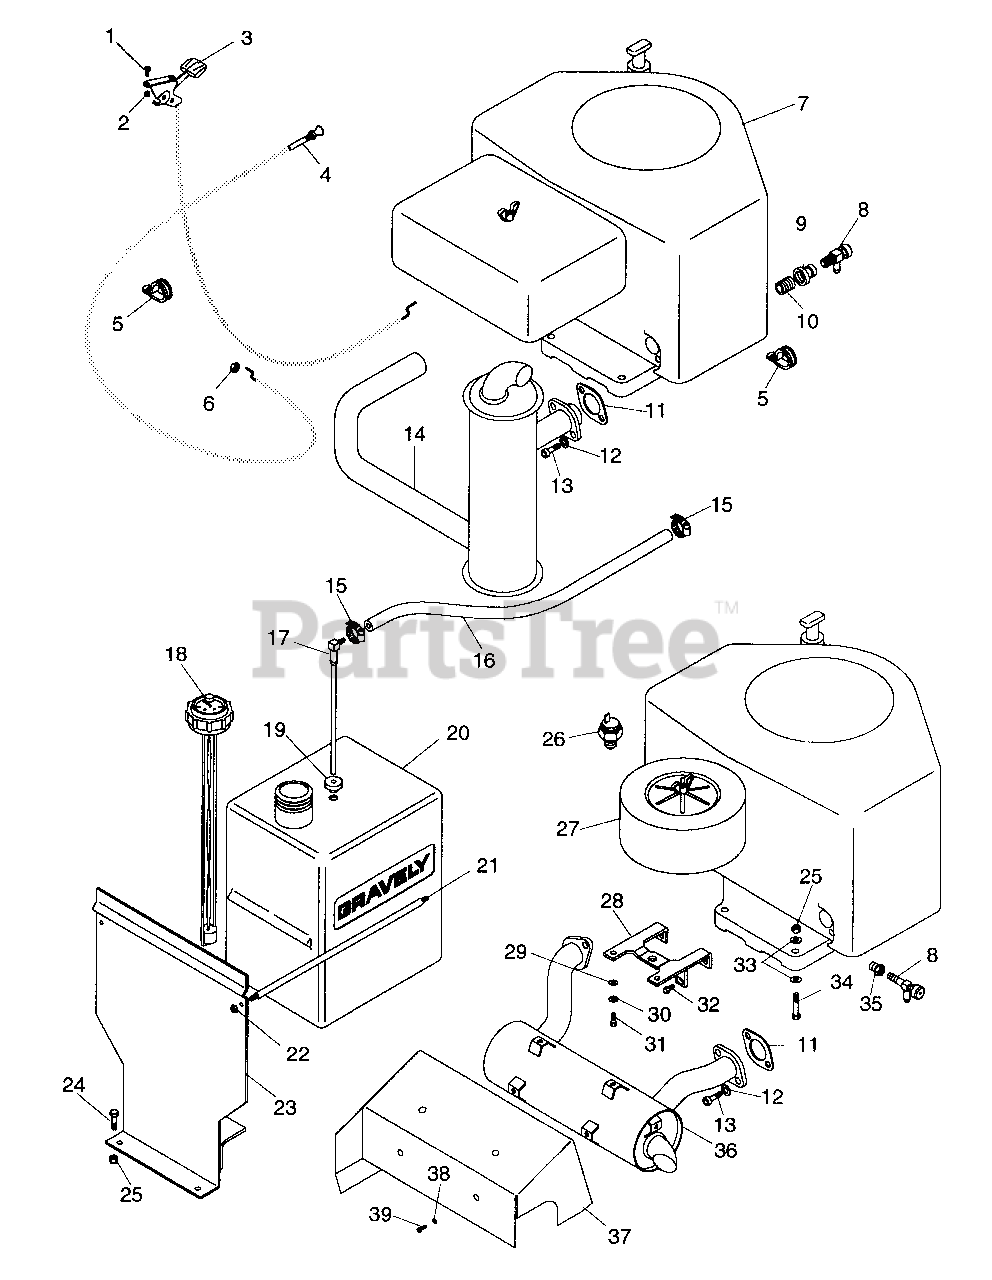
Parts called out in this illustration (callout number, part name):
1	Screw-Machine 10-24 x .50
2	Nut-Locking 10-24
3	Lever, Control
4	Control, Choke
5	Clamp, Cushioned Steel
6	Nut-Jam .375-24
7	Engine, 20-HP Onan
8	Cock, Oil Drain
9	Coupling, Reducing 3/8 x 1/4
10	Nipple, 3/8 Close
11	Gasket, Exhaust
12	Washer-Lock .313 x .078
13	Screw-Cap .31-18 x .75
14	Muffler Onan
15	Hose Clamp
16	Gas Line, Bulk
17	Fitting, Tank
18	Gauge, Fuel
19	Bushing
20	Tank, Fuel
21	Rod, Tank
22	Nut-Locking-Nylon .250-20
23	Weldment, Tank Bracket
24	Bolt-Hex .31-18 x .88 Grade 5
25	Nut-Locking-Nylon .312-18
26	Switch, Pressure
27	Engine, 18 HP Magnum, PS-58550
27	Engine, 20 HP Kohler, PS-57513
27	Engine, 20 HP Onan
28	Bracket, Muffler Support
29	Washer-Flat-Steel .281 x .620 x .065
30	Washer-Lock .250
31	Bolt-Hex .25-20 x .75 Grade 5
32	Scr-Tap .25-20 x .50 Hxslhdpl
33	Washer-Flat-Steel .344 x .688 x .065
34	Bolt-Hex .31-18 x 1.75 Grade 5
35	Adapter, Oil Drain
36	Muffler, Pro Master 18-H
37	Shield, Muffler
38	Washer-Flat-Steel .219 x .500 x .049
39	Screw-Drive 8-18 x .50
